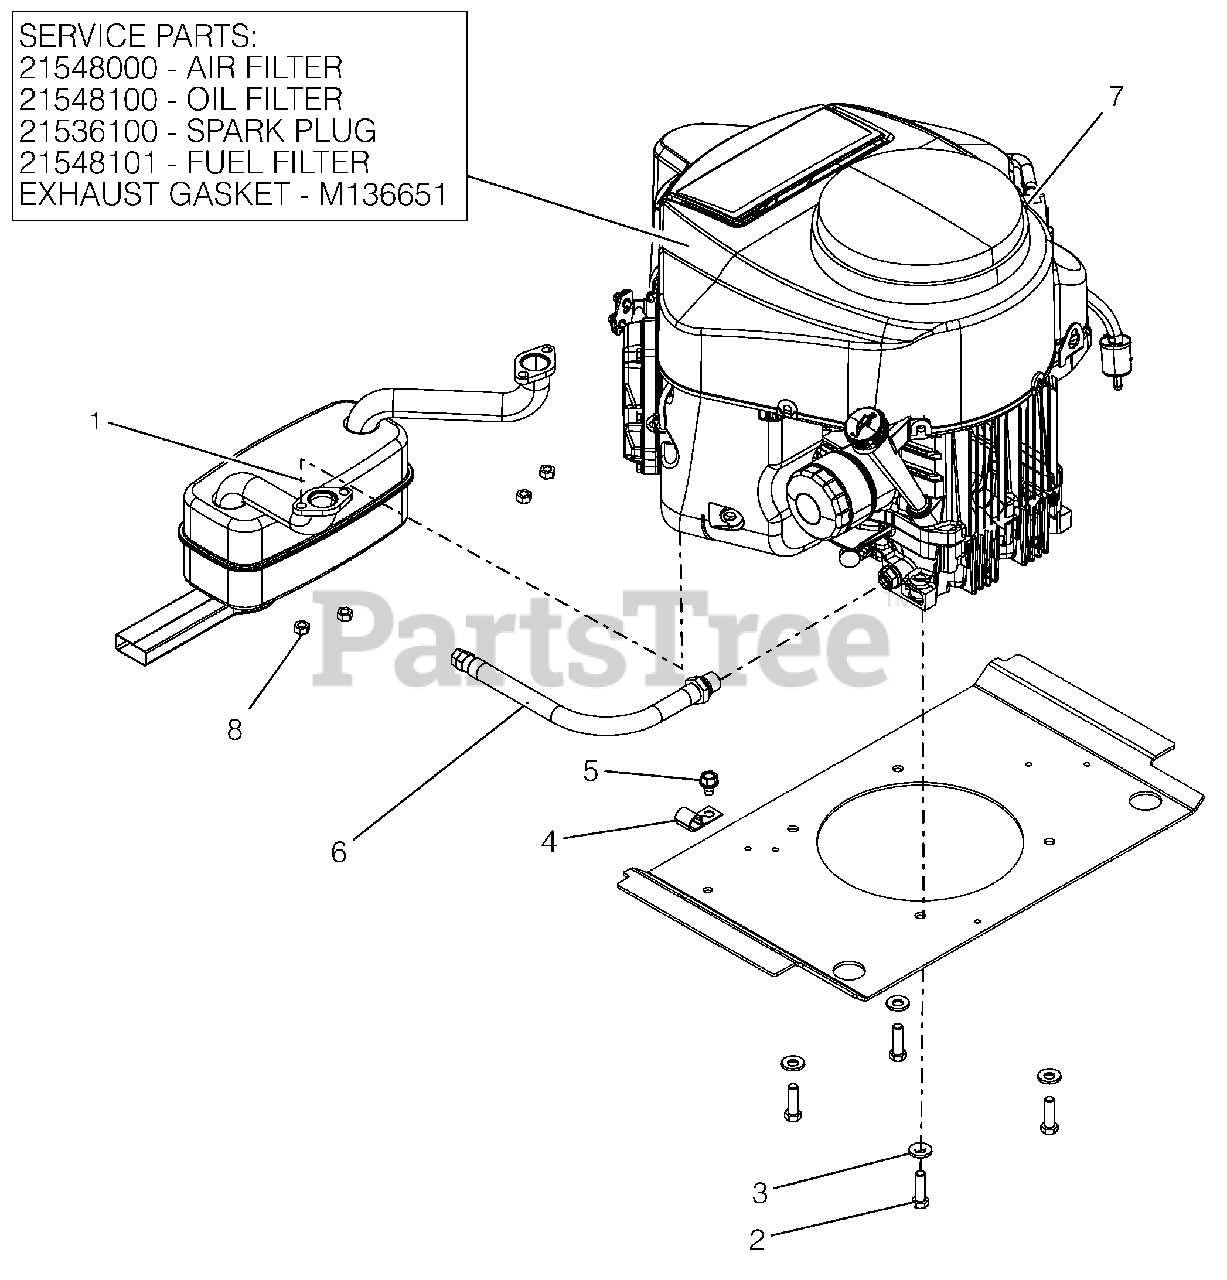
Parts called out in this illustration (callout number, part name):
1	MUFFLER, KAWASAKI
2	BLT-HEX.38-16X1.25 G5YZ NYTORQ
3	WASHER, 3/8" SPRING DISC
5	@SCR-TAP .38-16X.50 HWH TR YWZ
6	HOSE, OIL DRAIN
7	ENGINE, KAWASAKI FR651V
7	AIR FILTER, KAWASAKI FR
7	OIL FILTER, KAWASAKI FR
7	PLUG, SPARK
7	FUEL FILTER-KAWASAKI FR
7	GASKET, MUFFLER #
8	NUT-LK-TOP M8-1.25 YWZC
